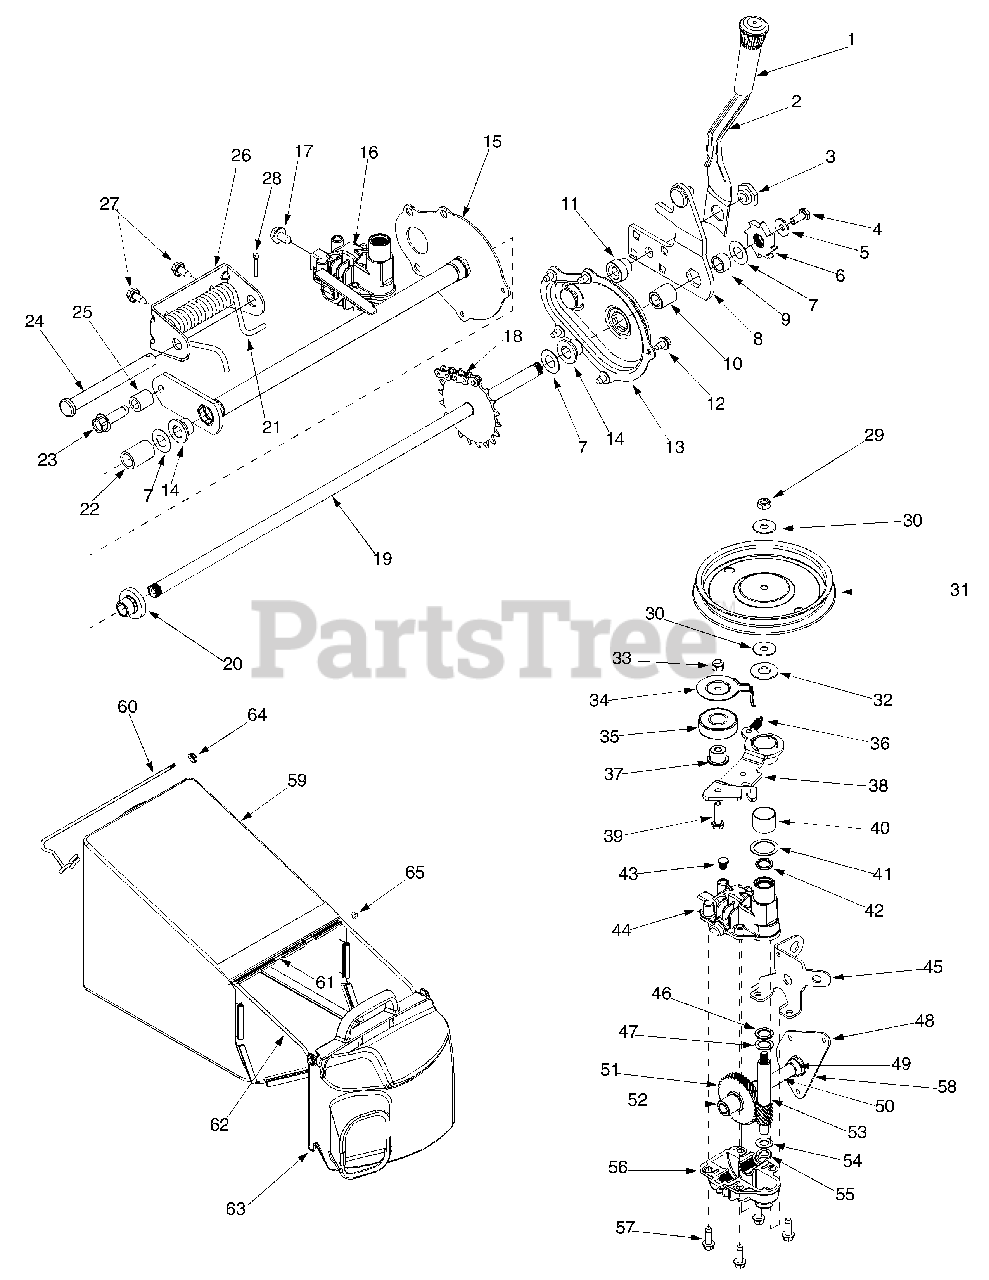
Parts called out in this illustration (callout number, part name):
2	Spring Lever
3	Shoulder Nut.825 x.165 Lg.
4	Cap Screw 1/4-20 x.620
5	Bell Washer.285 ID x.75 OD
6	Wheel Rachet
7	Flat Washer.508 ID x 1.0 OD
9	Spacer.510 ID x.70 OD
10	Sleeve Bearing.504 ID x.830 OD
11	Shoulder
12	Tap Screw 1/4-20 x.375
16	Transmission Assembly
17	Hex Screw 5/16-18
18	Chain
19	Rear Axle Assembly
20	Flange Bearing.506 ID x.715 Lg
21	Torsion Spring
22	Spacer.550 ID x.750 OD
23	Screw 3/8-16 x.25
24	Clevis Pin.50 Dia x 4.82 Lg.
25	Spacer.385 ID x.624 OD
28	Cotter Pin
29	Hex Jam Nut 5/16-24
30	Bell Washer.325 ID x.930 OD
32	Flat Washer.510 ID x 1.120 OD
33	Hex Jam Nut 1/4-28
34	Belt Keeper
35	Bearing
36	Extension Spring
37	Flange Spacer
38	Idler Bracket Assembly
39	Hex Cap Screw 1/4-28 x 1.0
40	Bearing Sleeve
41	Flat Washer.885 ID x 1.45 OD
42	Oil Seal
44	Upper Housing Assembly
47	Thrust Washer.504 ID x.70 OD
48	Pivot Bracket
49	Flange Bearing
50	Output Shaft 6T
52	Bearing
53	Pinion Shaft 10T
54	Thrust Washer 3/8 x.70
55	Thrust Washer.388 x.625
56	Lower Housing Assembly
57	Hex Screw 1/2-20 x.75
58	Shaft Assembly
59	Grassbag
61	Pivot Rod
63	Grassbag Cover
64	Flange Lock Nut, 5/16-18
65	Speed Nut
